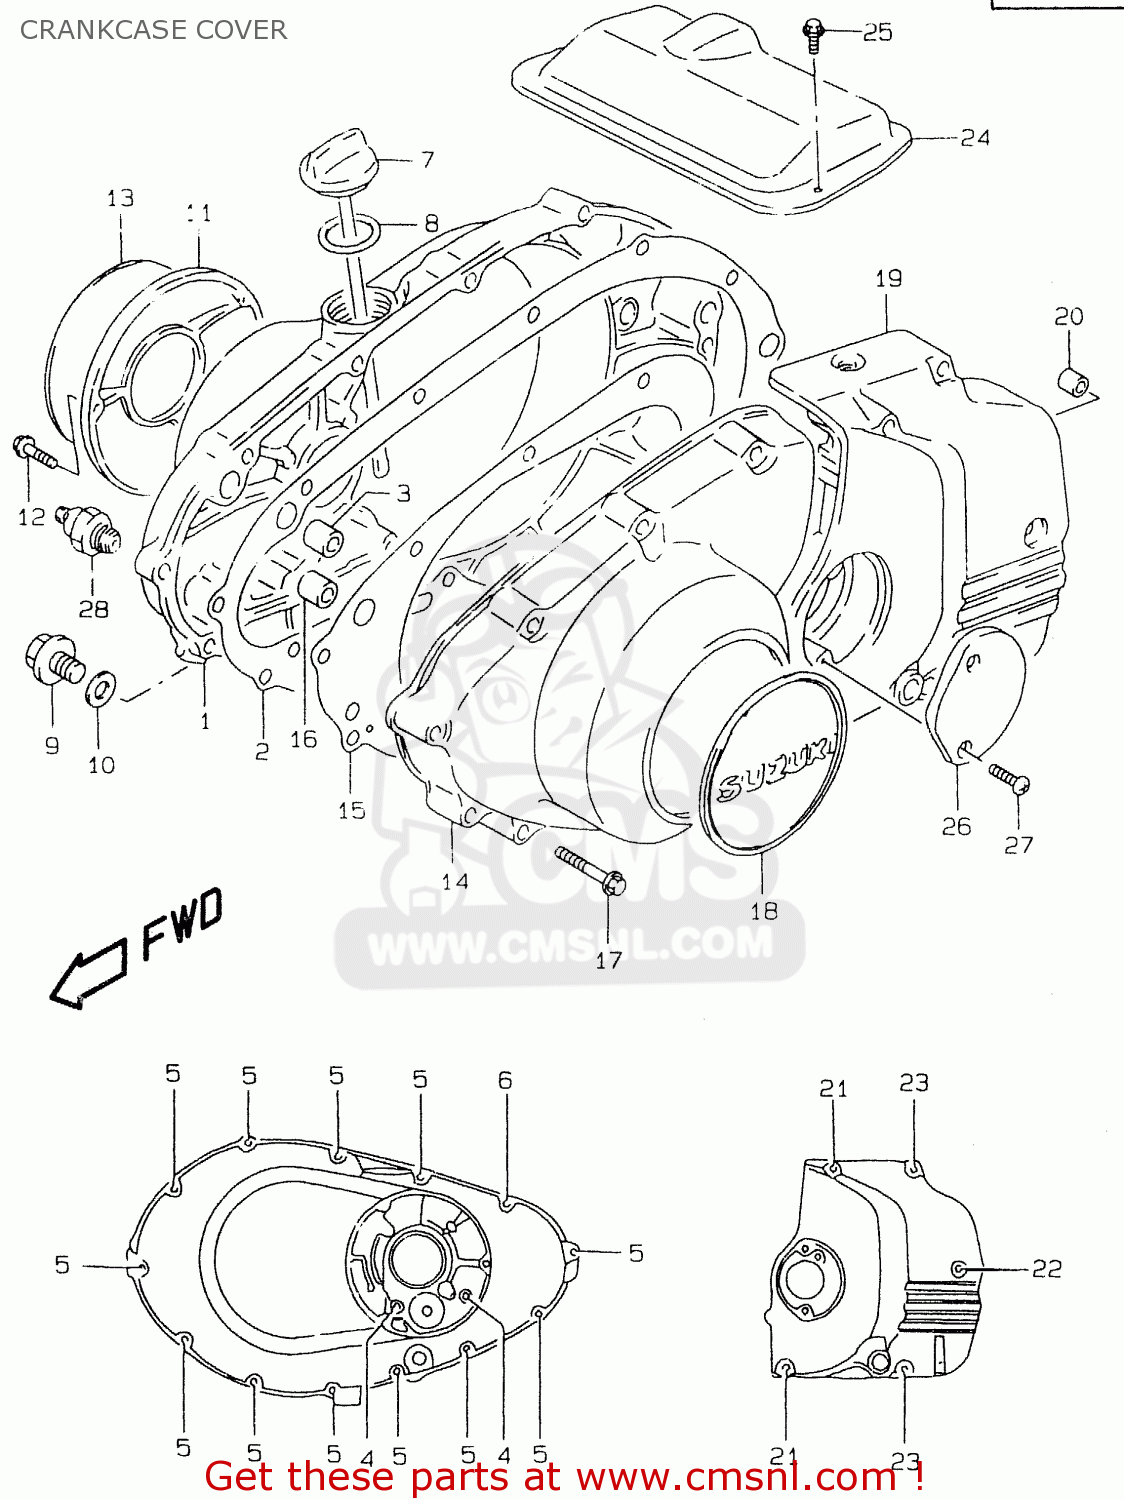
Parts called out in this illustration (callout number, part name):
1	COVER,CLUTCH
2	GASKET,CLUTCH COVER (NAS)
3	PIN
4	BOLT
5	BOLT
6	BOLT
7	GAUGE,OIL LEVEL
8	O RING(D:3.1,ID:26.4)
9	PLUG(14X12)
10	GASKET(13.8X18.8X4.8) (NAS)
11	COVER,CONTACT BREAKER
12	BOLT
13	EMBLEM,CONTACT BREAKER COVER
14	COVER,MAGNETO
15	GASKET,MAGNETO COVER (NAS)
16	PIN
17	BOLT
18	EMBLEM,CONTACT BREAKER COVER
19	COVER,ENGINE SPROCKET
20	PIN
21	BOLT
22	BOLT
23	BOLT
24	COVER,STARTER MOTOR
25	BOLT
26	CAP,CLUTCH RELEASE ADJUST
27	SCREW
28	SWITCH ASSEMBLY,OIL PRESSURE
